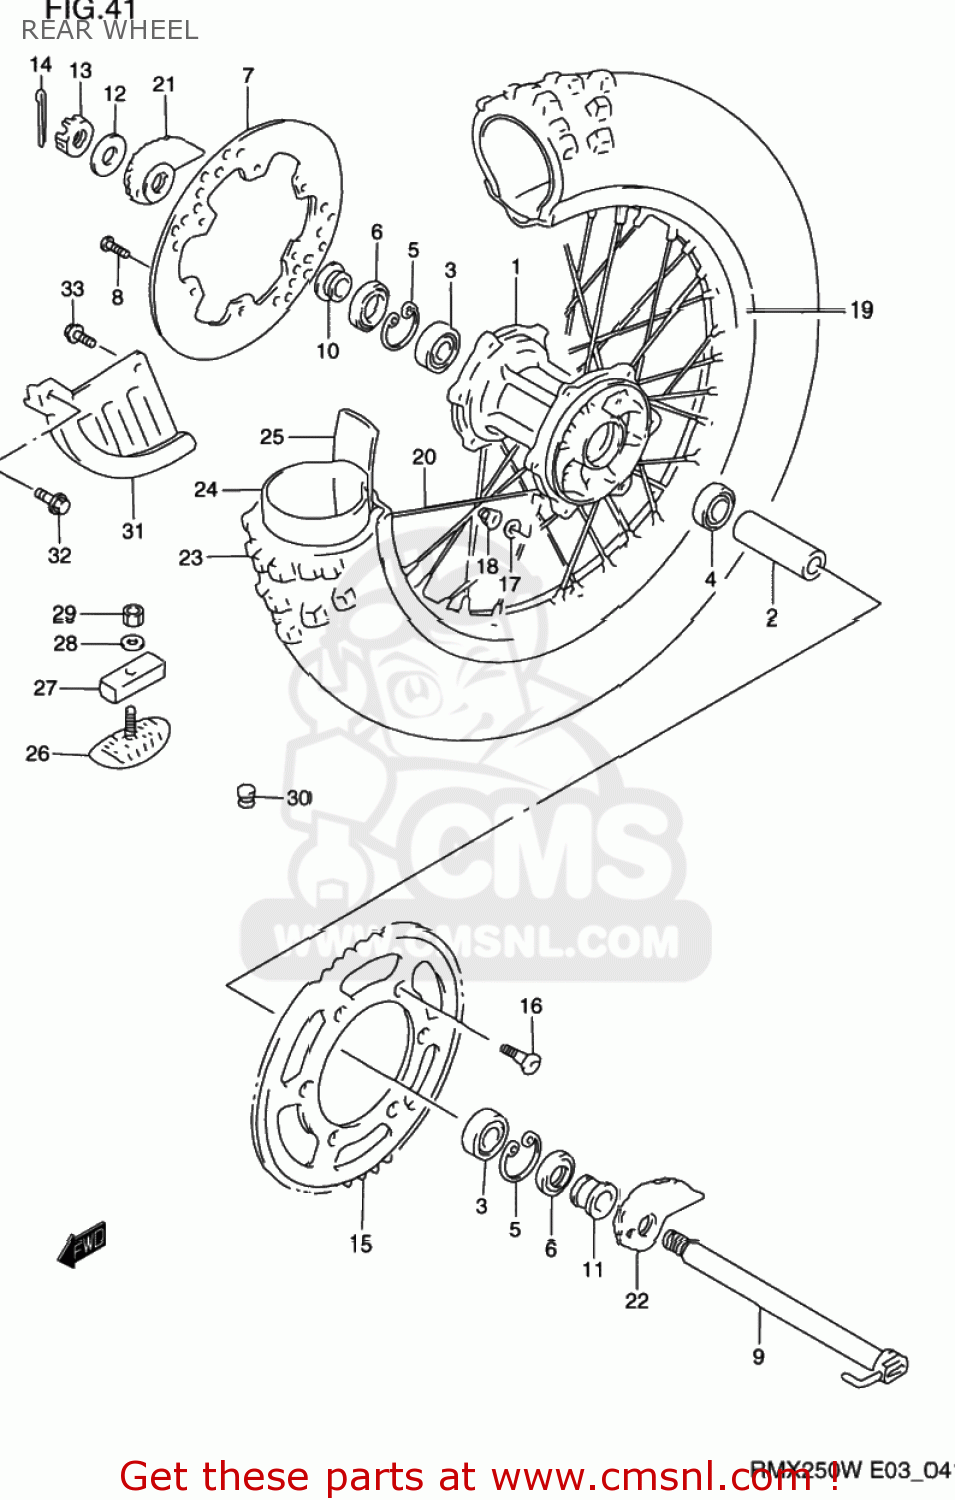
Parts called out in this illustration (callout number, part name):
1	HUB,RR
2	SPACER,RR HUB BEARING
3	BEARING WHEEL REAR(20X47X14)
4	BALL BEARING
5	CIRCLIP,14MM
6	SEAL,OIL(26X47X5)
7	DISC,RR BRAKE
8	SCREW
9	AXLE,RR
10	SPACER,RR AXLE,R
11	SPACER,RR AXLE,L
12	WASHER(19X32X3.2)
13	NUT
14	PIN,COTTER
15	SPROCKET,RR(NT:50)
16	SCREW(8X33.5)
17	WASHER
18	NUT
19	RIM,REAR WHEEL (2.15X18)(A
20	SPOKE ASSY,RR WHEEL
21	ADJUSTER,CHAIN,R
22	ADJUSTER,CHAIN,L
23	TIRE,REAR 110/100-18
24	TUBE ASSEMBLY,WHEEL,INNER
25	PROTECTOR,INNER TUBE
26	STOPPER,BEAD(2.15)
27	CUSHION,BEAD STOPPER
28	WASHER
29	NUT
30	CAP(OD:12)
31	COVER SET,RR BRAKE DISC
32	BOLT
33	BOLT
